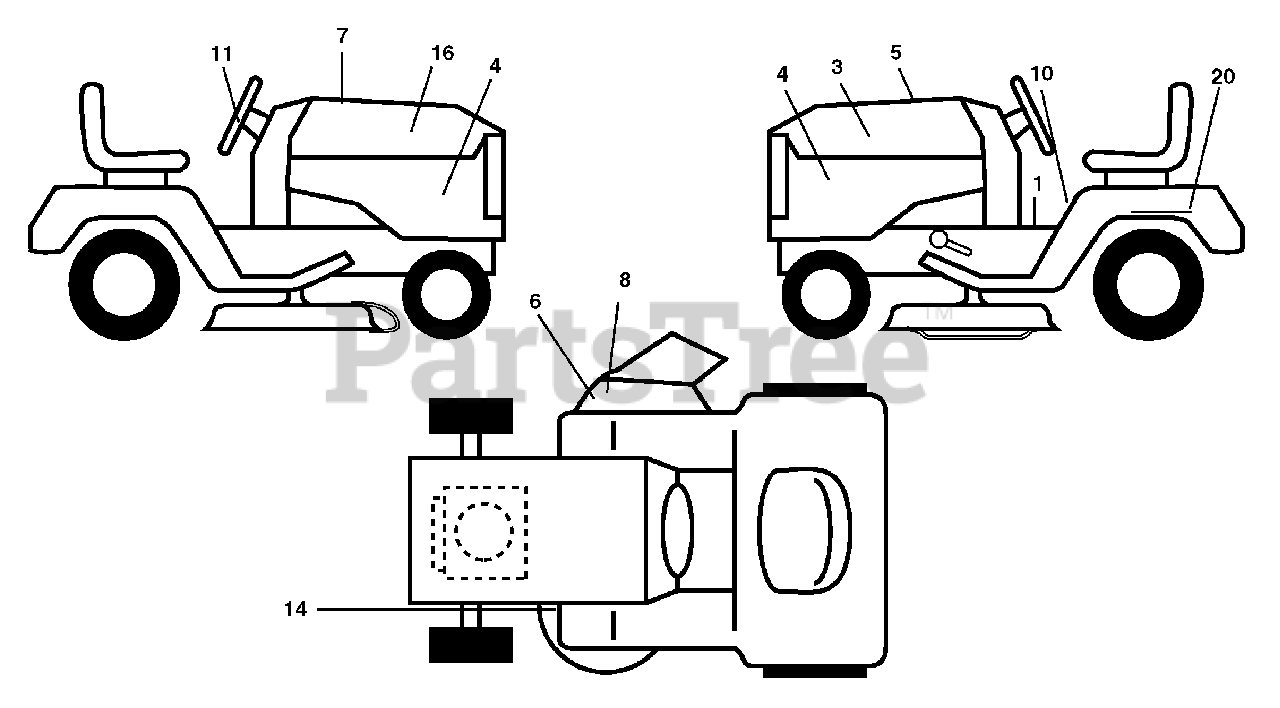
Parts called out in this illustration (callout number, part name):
1	Decal Oper
3	Decal Hood LH
4	Decal Side Panel Logo
5	Decal Hood Cust Resp.
6	Decal Warning, Keep Hand Away
7	Decal Replacement Parts
8	Decal Deck "B" 42"
10	Decal Fender Danger E/F
11	Decal Ins Strg Whl
14	Decal V-Belt Schematic
16	Decal Hood Rh
20	Decal Bat Dan/Psn
